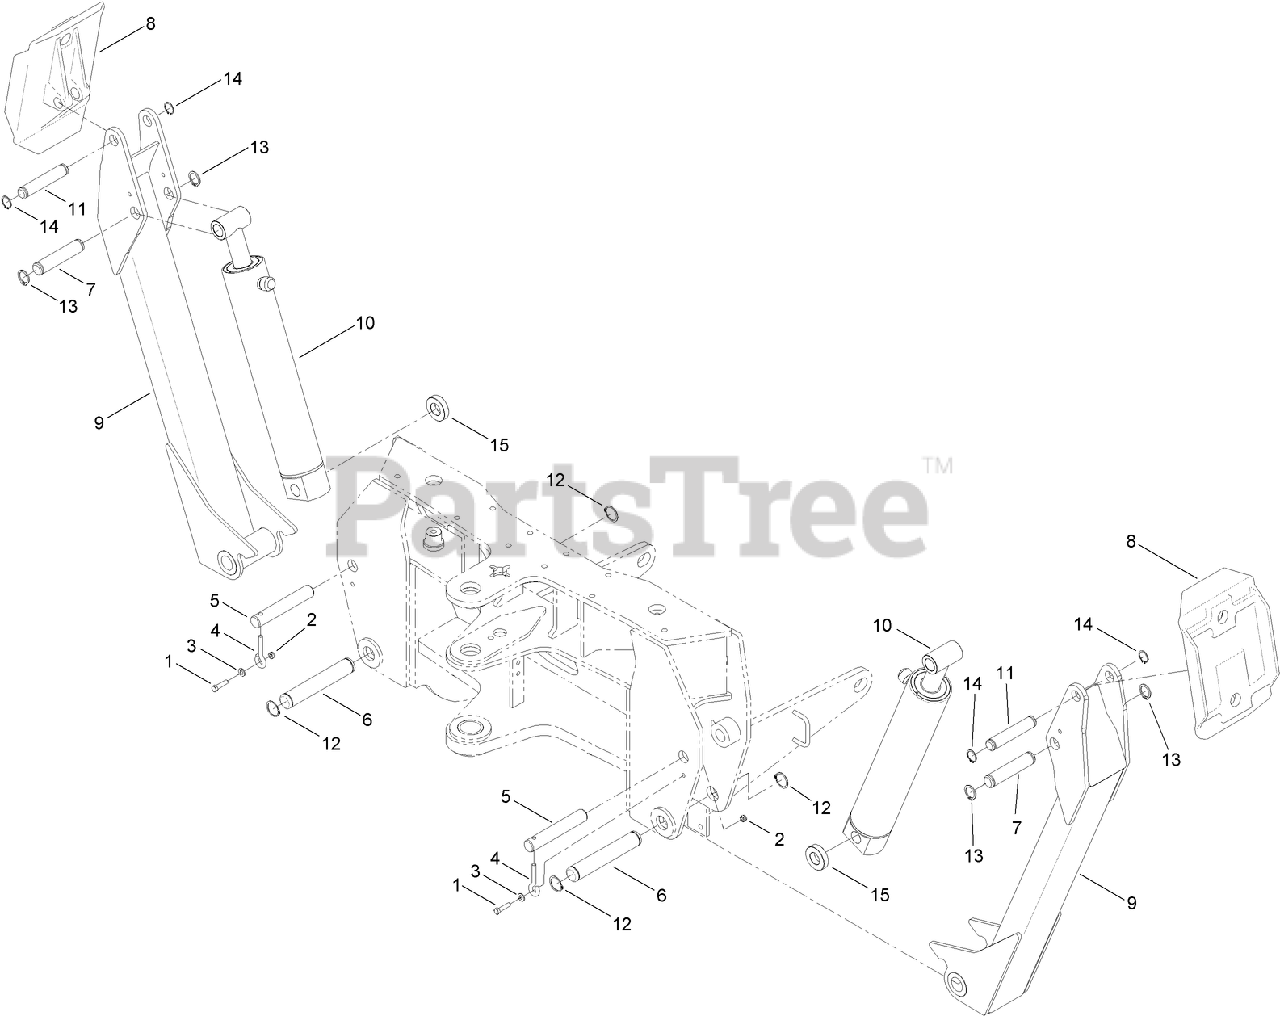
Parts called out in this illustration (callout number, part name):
1	SCREW-HH
2	NUT-HEX
3	WASHER-FLAT
4	PIN-RETAINER
5	PIN (CYLINDER TO FRAME)
6	PIN (STABILIZER TO FRAME)
7	PIN-STABILIZER (CYLINDER ROD END)
8	PAD-STABILIZER
9	STABILIZER
10	HYD CYLINDER ASM
11	PIN (STABILIZER PAD END)
12	RING-RETAINING, EXTERNAL
13	RING-RETAINING, EXTERNAL
14	Ring-Retaining
15	SPACER
